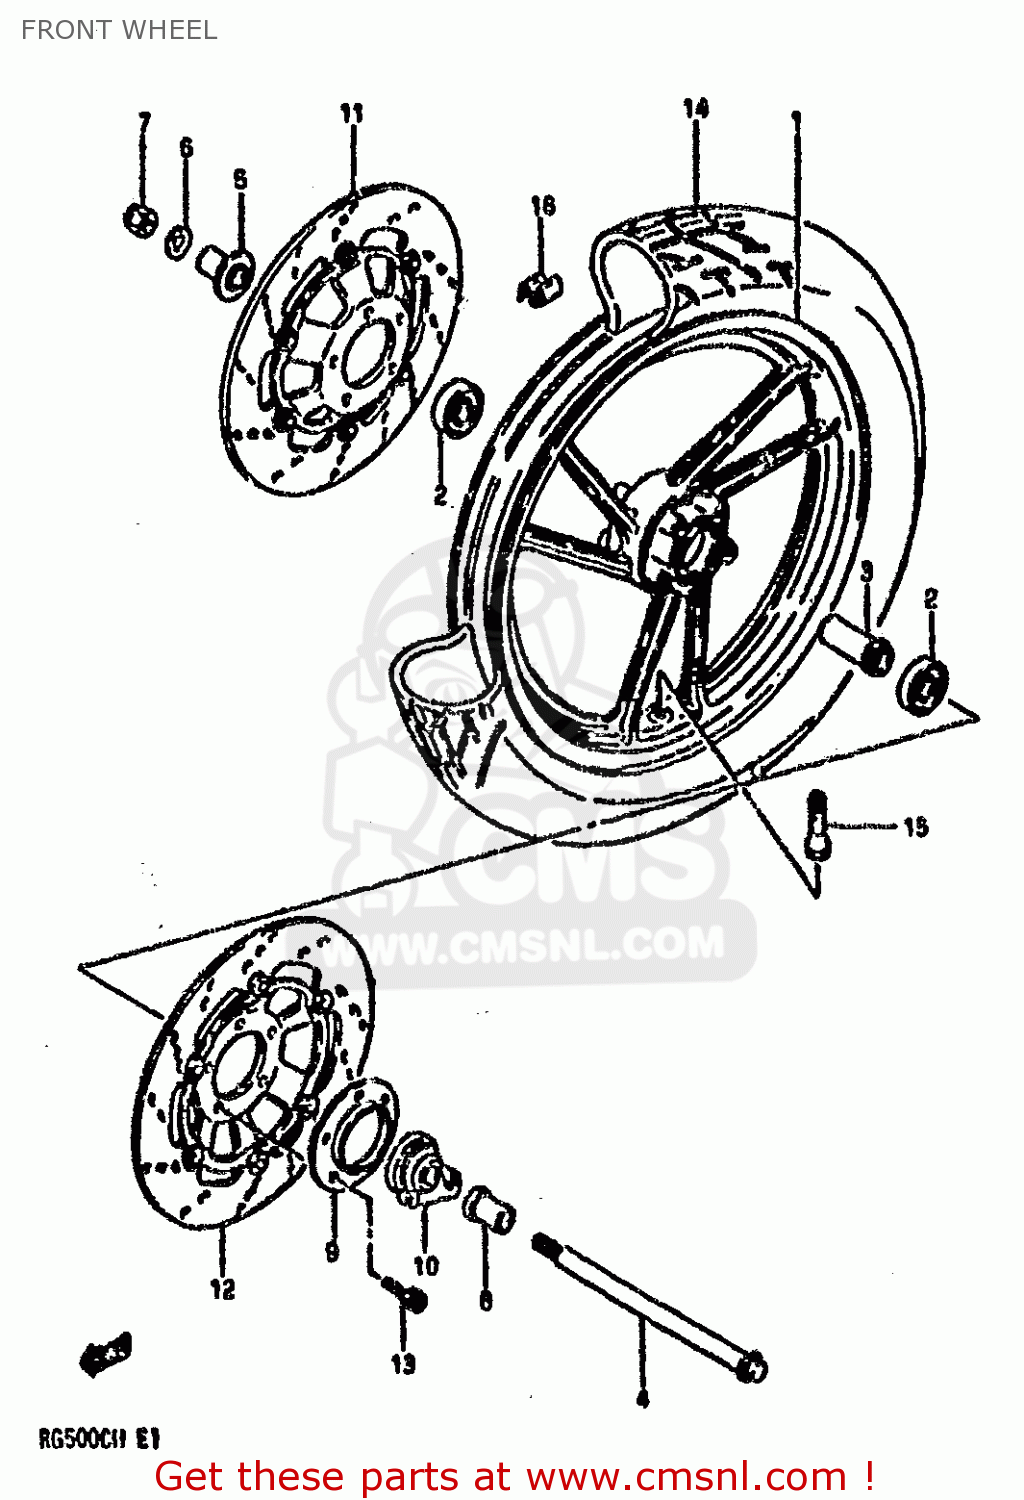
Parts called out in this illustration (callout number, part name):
1	WHEEL,FRONT (NT2.50X16) BLACK
2	BEARING
3	SPACER,FR HUB BEARING
4	AXLE FRONT
5	SPACER,FR AXLE
6	WASHER
7	NUT
8	SPACER,FR AXLE,L
9	DUST SEAL,SPEEDOMETER BOX
10	BOX ASSY,SPEEDOMETER GEAR
11	DISC COMP,R
12	DISC,FR.BRAKE
13	BOLT(8X28)
14	TIRE,T/L FRONT (110/90V16)
15	VALVE,TIRE
16	BALANCER,WHEEL
